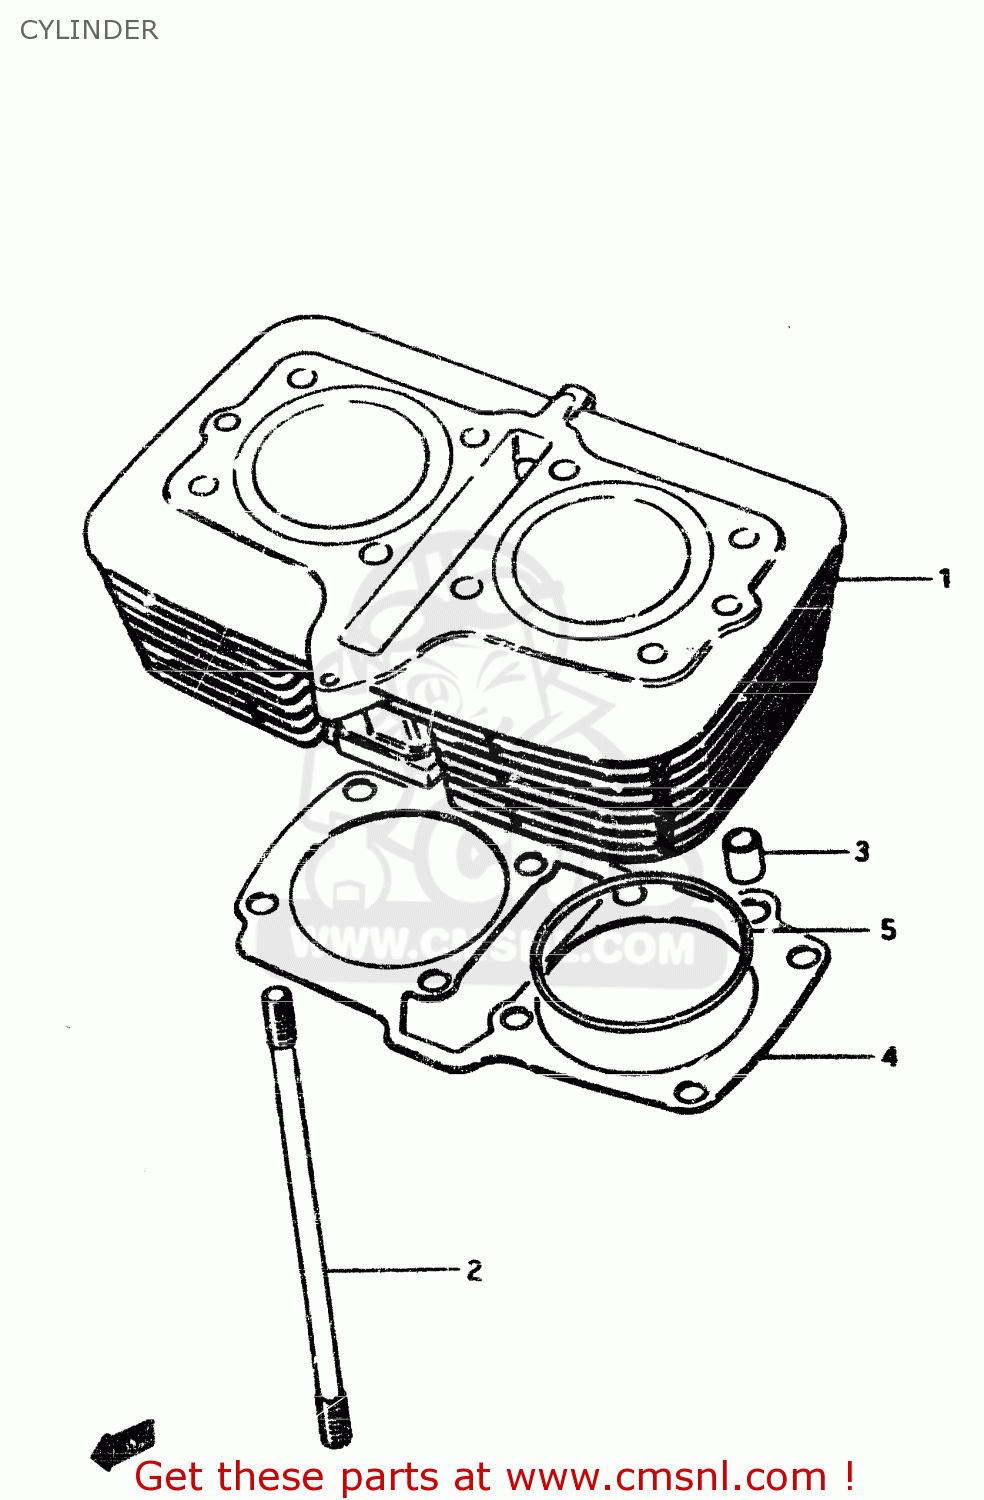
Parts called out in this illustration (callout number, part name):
1	CYLINDER
2	STUD
3	PIN
4	GASKET,CYLINDER (MCA)
5	O RING(D:2,ID:74)
